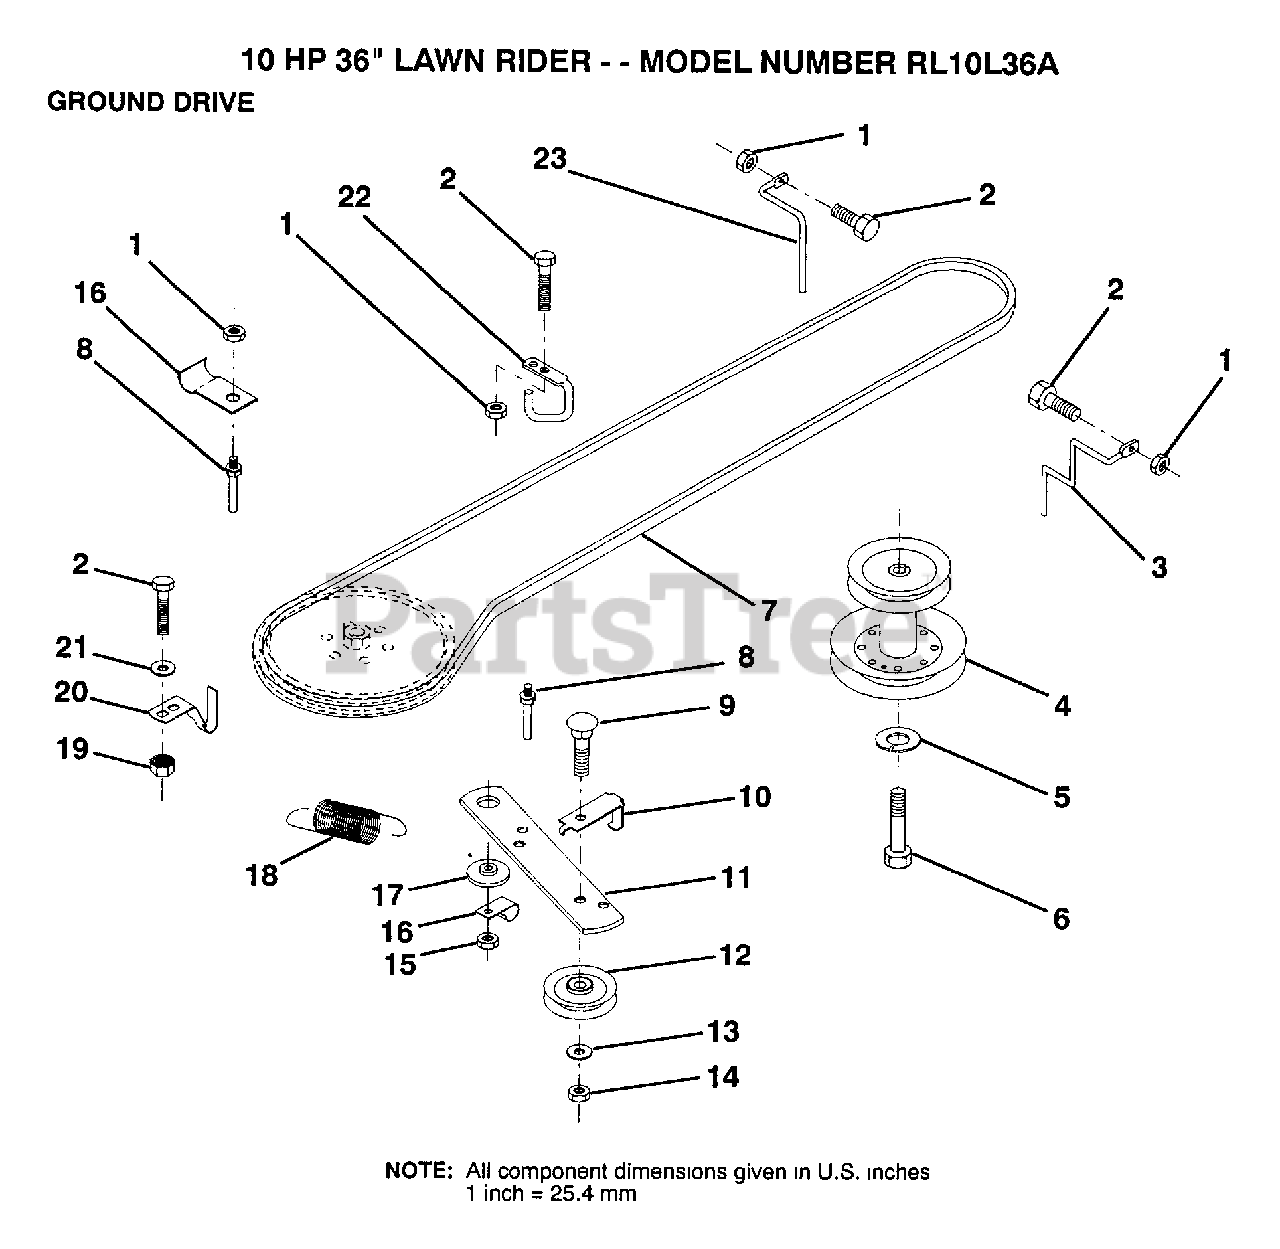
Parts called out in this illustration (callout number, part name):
2	BOLT
5	LOCKWASHER
6	HEX BOLT
7	BELT
8	"KEEPER,DRIVE BELT"
9	BOLT
10	"KEEP,IDLER DR BEL"
13	WASHER
14	LOCKNUT
16	"CLIP,INSULATOR"
17	SPACER RETAINER
20	"KEEPER,DR BELT "
21	WASHER
22	"KEEPER,FRA DR BEL"
